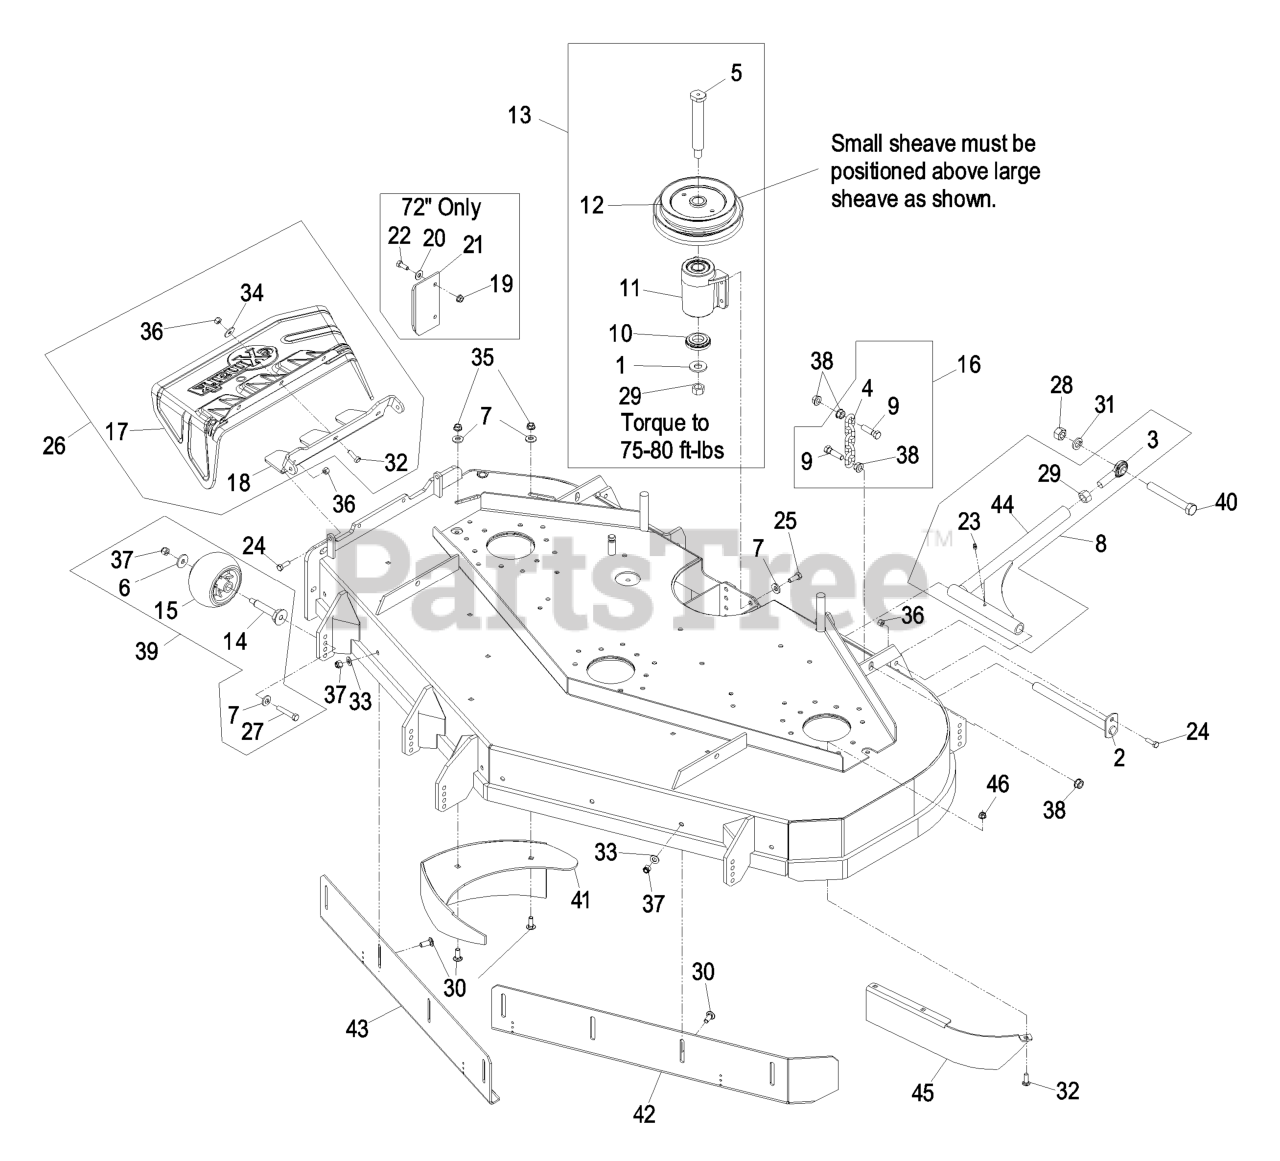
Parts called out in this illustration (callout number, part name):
1	WASHER-SPRING
2	PIN-STRUT
3	BALLJOINT-SPHERICAL
4	CHAIN-LIFT, DECK
5	JACKSHAFT
7	WASHER-BELLEVILLE
8	ASM,DECK STRUT XS 60
9	SCREW-HH
10	SPACER-GUARD, BOTTOM
11	KIT, JACKSHAFT ASSY
12	SHEAVE, JACKSHAFT DOUBLE
13	KIT,JACKSHAFT 60/72-3750
15	ROLLER-SCALP, ANTI
16	DECK CHAIN ASM
17	CHUTE,DISCHARGE LZ
18	Hinge, Grass Discharge
20	WASHER-FLAT
21	DEFLECTOR,DISCHARGE
22	SCREW-HH
23	FITTING-GREASE
24	SCREW-HH
25	SCREW-HH
26	ASM, DISCHARGE CHUTE
27	SCREW-HH
28	NUT-HEX
29	NUT-HEX
30	SCREW-CARR
31	WASHER-LOCK
32	SCREW-CARR
33	WASHER-FLAT
34	WASHER-FLAT
35	NUT-HHF, WHIZ
36	NUT-LOCK, NI
37	NUT-LOCK, NI
40	SCREW-HH
41	WLD,DOGLEG 605
42	WLD,BAFFLE FRT ADJ LH 605
43	WLD,BAFFLE FRT ADJ RH 605
45	BAFFLE,SCROLL 605
46	NUT-HF, NI
